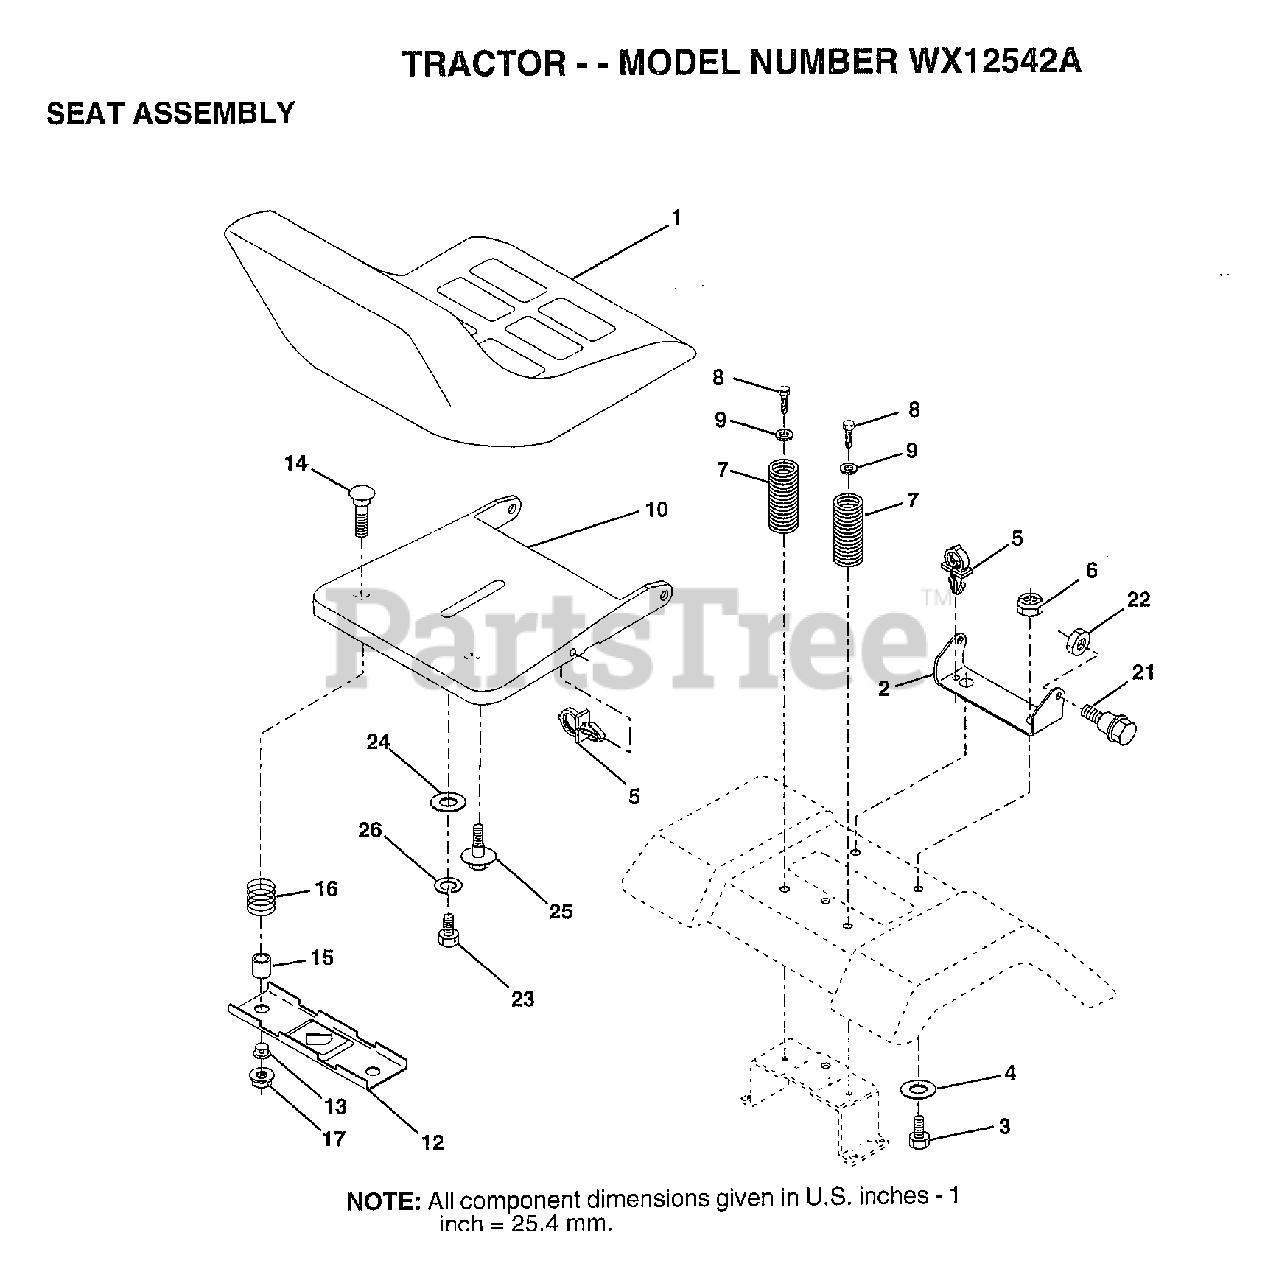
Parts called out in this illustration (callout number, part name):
2	BRACKET PVT SEAT
3	BOLT
4	WASHER PM
5	CLIP.PUSH-IN.HING
6	NUT
7	SPRING COMPRESSIO
8	SCREW GTV
9	WASHER
12	BRKT SWITCH
13	BUSHING
15	SPLIT SPACER
16	SPRING
21	BOLT.SHLD.5/16-18
22	NUT
23	BOLT
24	WASHER
25	"BOLT,SHOULDER"
26	LOCKWASHER
